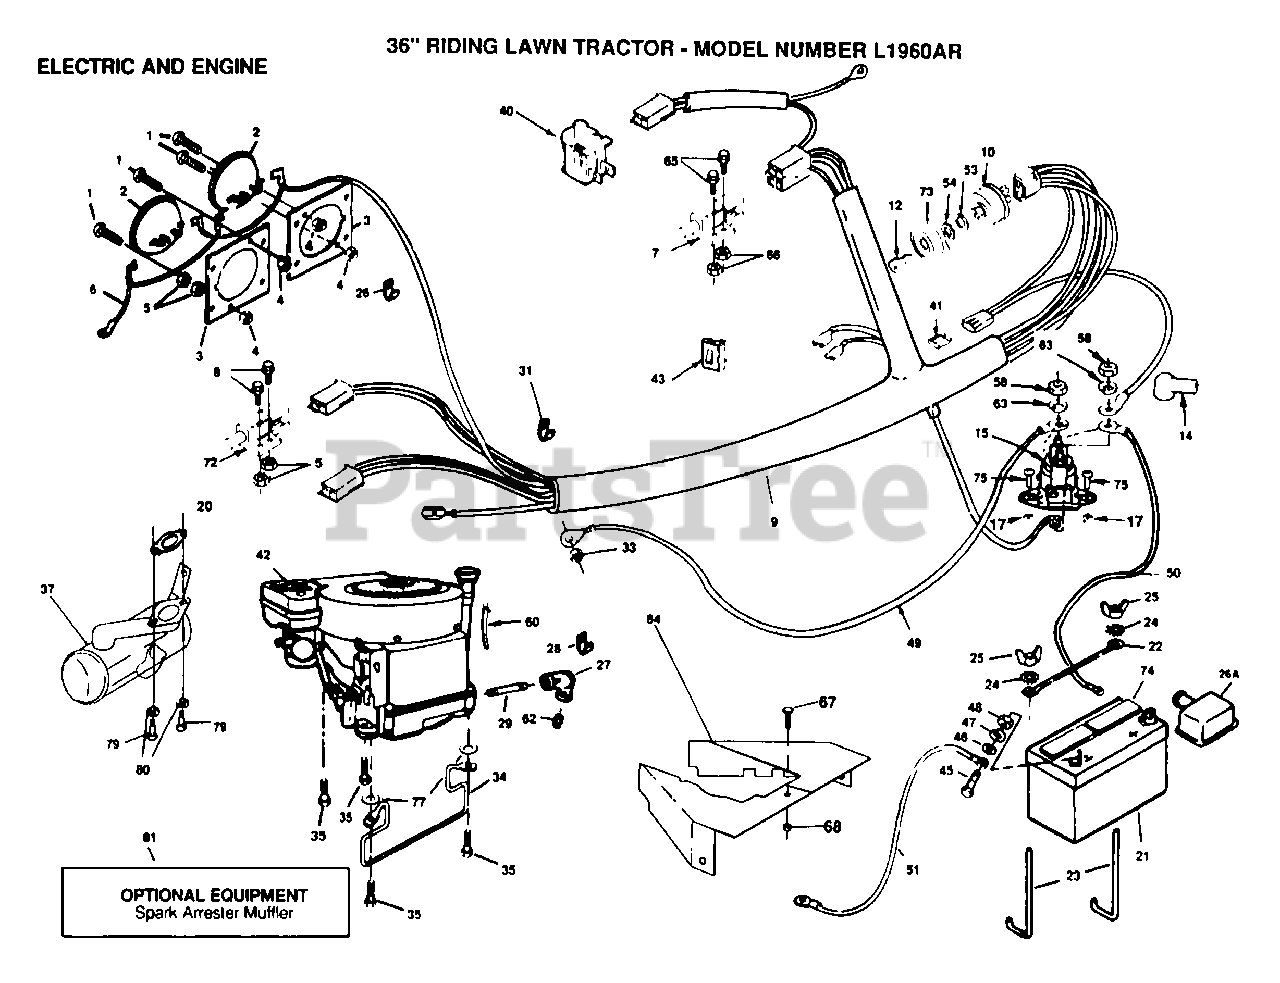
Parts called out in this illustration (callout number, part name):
7	SWITCH INTERLOCKT
8	SCREW
17	NUT
22	"ROD, BATTERY"
23	"BOLT, BATTERY"
24	LOCKWASHER GT
26	CLIP SB
26A	BATTERY TERMINAL COVER
27	ELBOW
28	INSUL CLIP T
29	PIPE NIPPLE
34	BELT KEEPER LT
35	SCREW LT
40	SWITCH SEAT
41	FUSE HYT
43	SWITCH LT
45	BOLT LT
46	WASHER PM
47	LOCKWASHER
49	"CABLE T, BATTERY"
53	WASHER T
58	NUT
60	WIRE TIE
62	PLUG OIL DRAIN
65	SCREW
66	"NUT,KEPS"
72	SWITCH-INTER. GT
74	"CAP,BATTERY "
75	"SCREW,MACHINE"
77	WASHER
79	BOLT
80	LOCKWASHER
81	SPARK ARRESTER KIT
